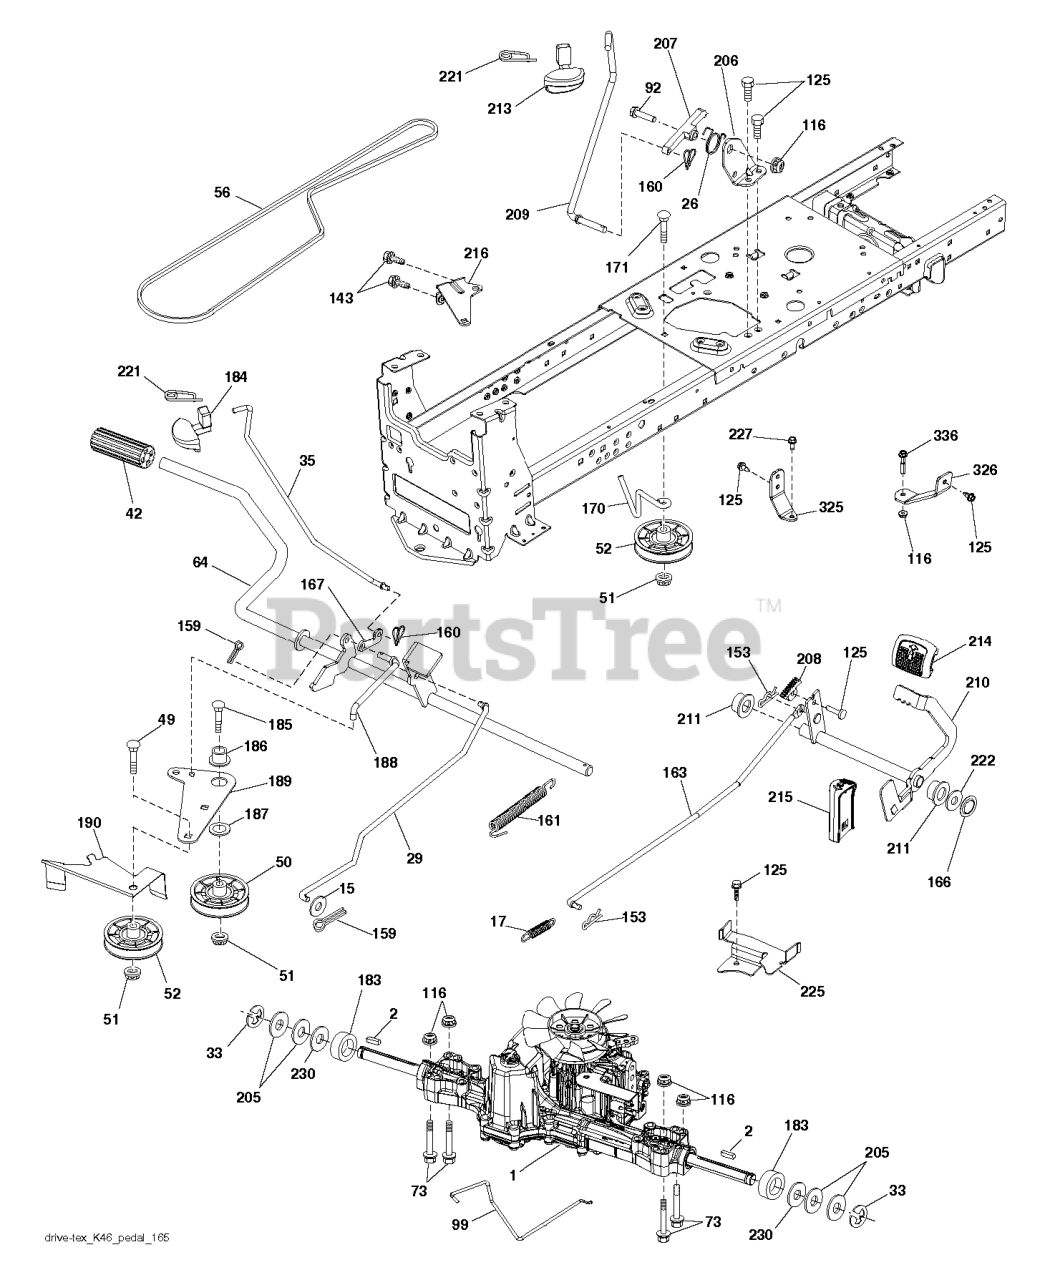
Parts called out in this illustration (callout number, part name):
2	SQUARE KEY
15	WASHER
17	SPRING.BRAKE.K46.GREEN
26	SPRING.RETURN.CRUISE
29	ROD.BRAKE.K46
35	ROD .BRAKE. PARKING. GT. HUSQ.
42	PEDAL COVER T
50	IDLER.FLAT.910.OFFSET
51	NUT LOCK FLG 3/8-16 UNC
52	IDLER.V-GROOVE.910.OFFSET
56	V-BELT.MOWER.92.40.42/K46
64	SHAFT.ASM.PEDAL.BRK.CNTR
73	BOLT
80	STRAP.TORQUE.K46.K57R.TT
92	BOLT
99	ROD.SPRING.BYPASS.K46.LT.Z
116	NUT LOCK HEX FLANGE 5/16-18
125	SCREW
143	SCREW LT
153	RETAINER M
159	COTTER PIN
160	RETAINER CLIP
161	SPRING, RETURN LT
163	ROD.CONTROL.K57R.K46
166	NUT.PUSH.625
167	LATCH.BRAKE.SPRING
170	KEEPER.V-IDLER.CENTER.
171	BOLT
183	SPACER AXLE
184	RB HANDLE.PARKG.BRK.HUS/PRED
186	SPACER.RETAINER
187	WASHER 12/32X2X10GA
188	RP.LINK.CLUTCH.GROUND.DRIVE
189	BELLCRANK.GROUND.DRIVE.TEX.
190	KEEPER.BELLCRANK.DRIVE
206	BRACKET.MOUNT.CRUISE.LATCH
207	LATCH.CONTROL.CRUISE
208	GEAR.SECTOR.CONTROL.CR
209	ROD.CONTROL.CRUISE.GT.
210	ROCKER.ASM.PEDAL.CONTR
211	BEARING.NYLON
213	KNOB.CONTROL.CRUSIE.HU
214	PEDAL.FORWARD.PAD.TEX
215	PEDAL.REVERSE.TEX.GT.4
216	BRACKET.PULLEY.IDLER.W/TEX
221	RETAINER.SPRING.CLIP.H
222	WASHER 21/32 X 1-1/4 X 10 GA.
225	KEEPER.BELT.TRANSAXLE.K46
226	BRACKET.MOUNT.TORQUE.K46.TLT
227	SCREW.THDROL.5/16-18X3/4.TTY
230	WASHER.HARDENED
